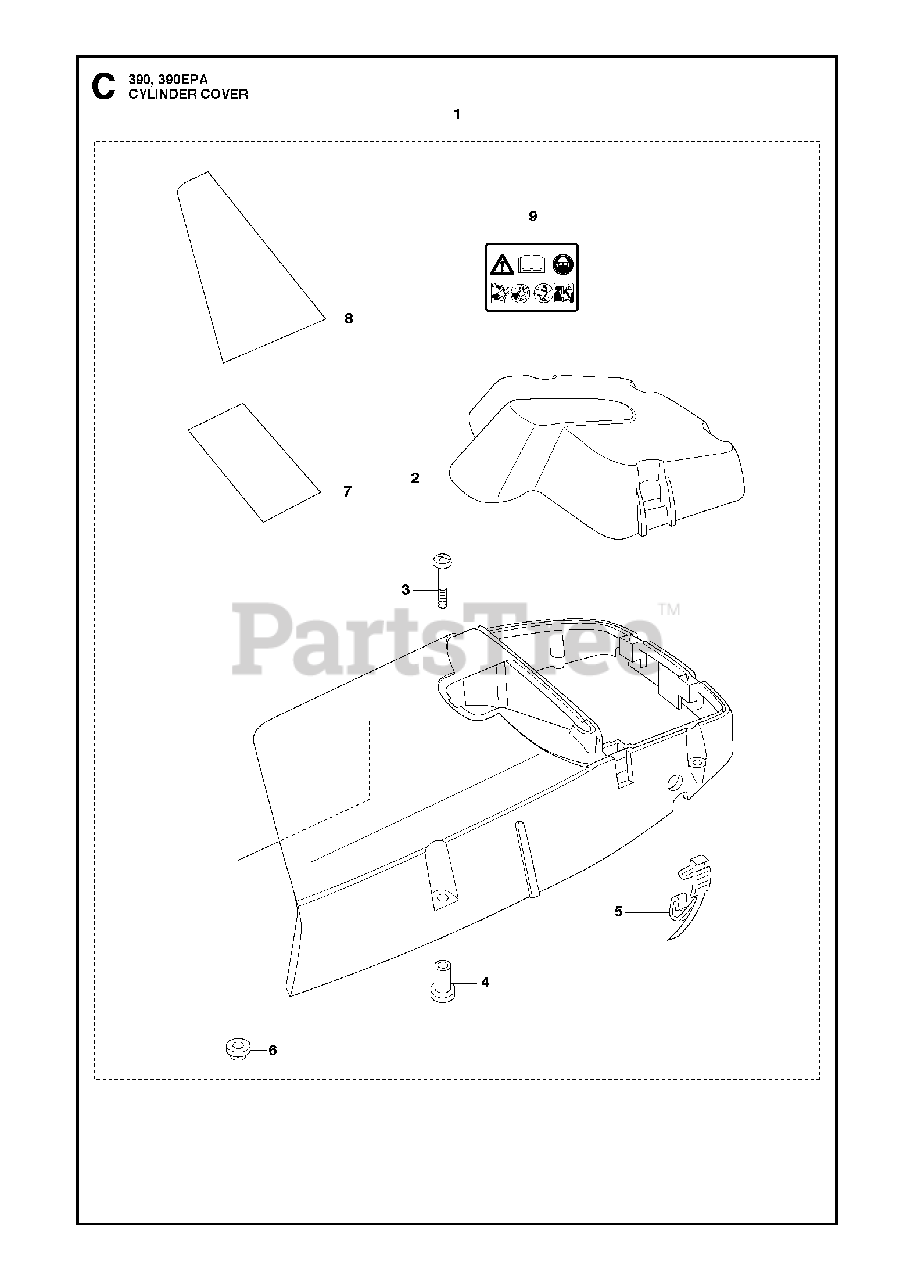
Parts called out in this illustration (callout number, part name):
1	CYLINDER COVER
2	COVER
3	SCREW
4	SLEEVE
5	HOLDER
6	GROMMET
7	PROTECTOR
8	PROTECTOR
9	DECAL
